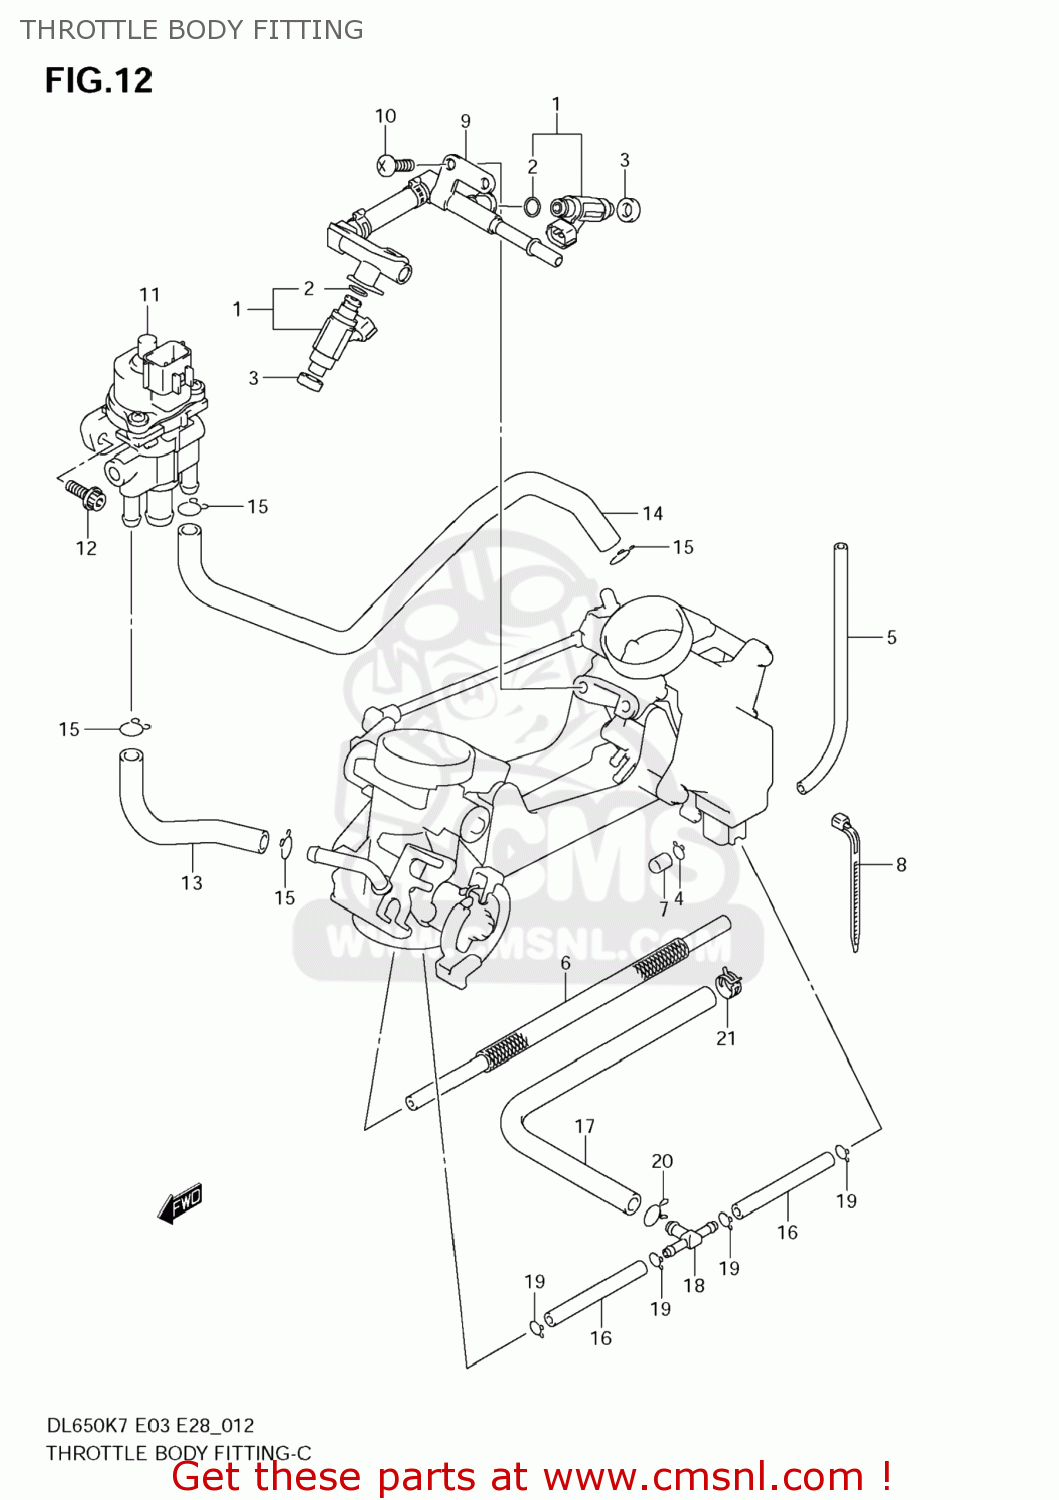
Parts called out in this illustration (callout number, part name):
1	INJECTOR ASSY
2	O RING
3	SEAL
4	CLIP
5	HOSE
6	HOSE
7	CAP
8	CLIP
9	DELIVERY PIPE ASSY
10	SCREW
11	VALVE,ISC
12	BOLT
13	HOSE,ISC VALVE FR
14	HOSE,ISC VALVE RR
15	CLIP
16	HOSE
17	HOSE
18	NIPPLE
19	CLIP
20	CLIP
21	CLIP
